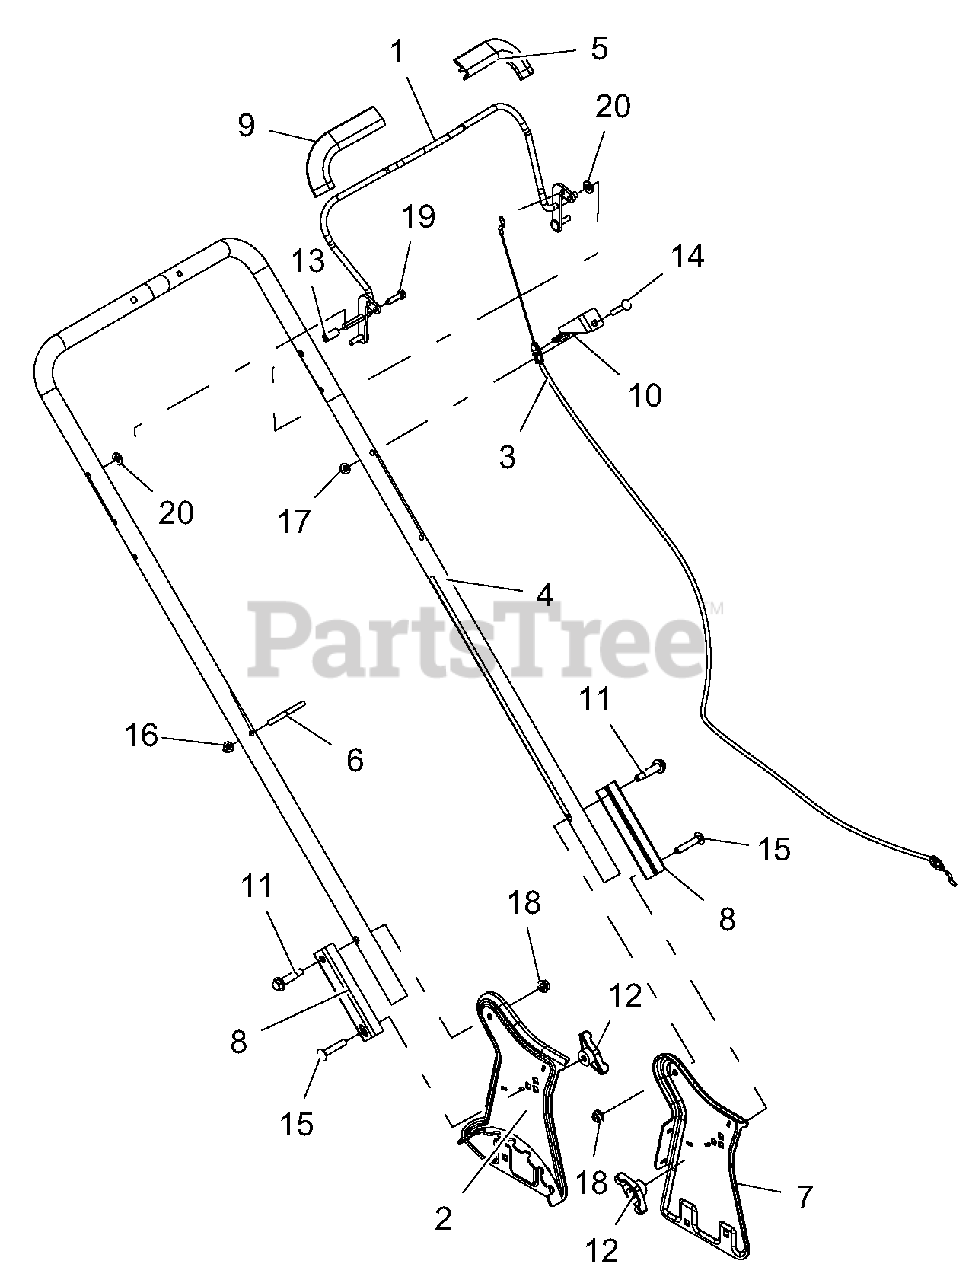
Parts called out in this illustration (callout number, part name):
1	BAIL, OPC
2	WLDMT, RH SIDE PLATE - ARIENS
3	CABLE, OPC
4	HANDLEBAR
5	GUARD, FINGER - LH
6	GUIDE, RECOIL ROPE
7	SUPPORT, LH HANDLEBAR
8	BRKT, HANDLEBAR FIXED ADJUST
9	GUARD, FINGER - RH
10	BRKT, CABLE ANCHOR - LM PUSH
11	BLT, SHLDR .50 x 1.30 x .38-16 GR5
12	KNOB, WING .31-18 UNC NYL/TALC
13	CAP, VINYL
14	BLT-RDHDSQNK .25-20 x 1.50 G5 Y
15	BLT-RDHDSQNK .31-18 x 1.75 G5 YWZC
16	NUT-LK-NYL-FLG .25-20 YWZC
17	NUT, LK-TOP-FLG .25-20 YWZC
18	NUT, LK-TOP-FLG .312-18 YWZC
19	SCR-TAP .25-20 x 1.00 HWH TR YZ
20	WSHR-FL-STL .344 x .688 x .065 YWZC
